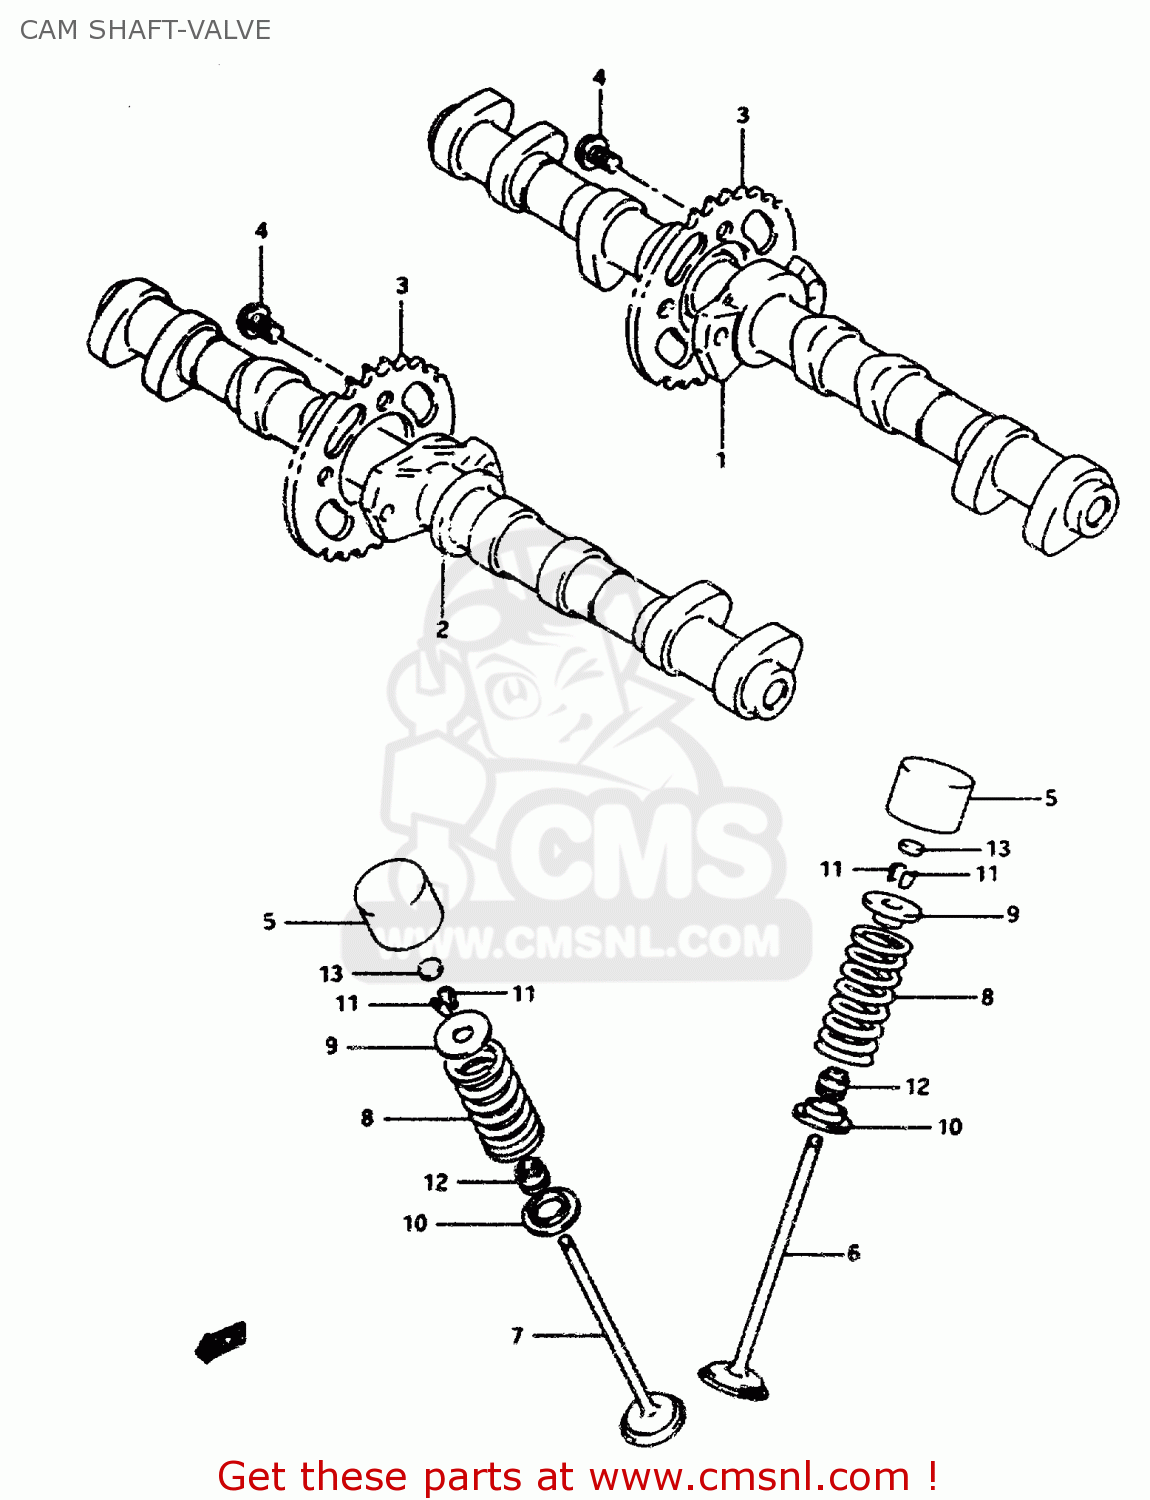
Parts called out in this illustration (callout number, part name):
1	CAM SHAFT,INTAKE
2	CAM SHAFT,EXHAUST
3	SPROCKET,CAMSHAFT
4	BOLT(7X11)
5	TAPPET
6	VALVE,INTAKE
7	VALVE,EXHAUST
8	SPRING,VALVE
9	RETAINER,VALVE SPRING
10	SEAT,VALVE SPRING
11	COTTER VALVE
12	SEAL,OIL(4.5X10X8)
13	SHIM,TAPPET
15	CASE,TAPPET SHIM
